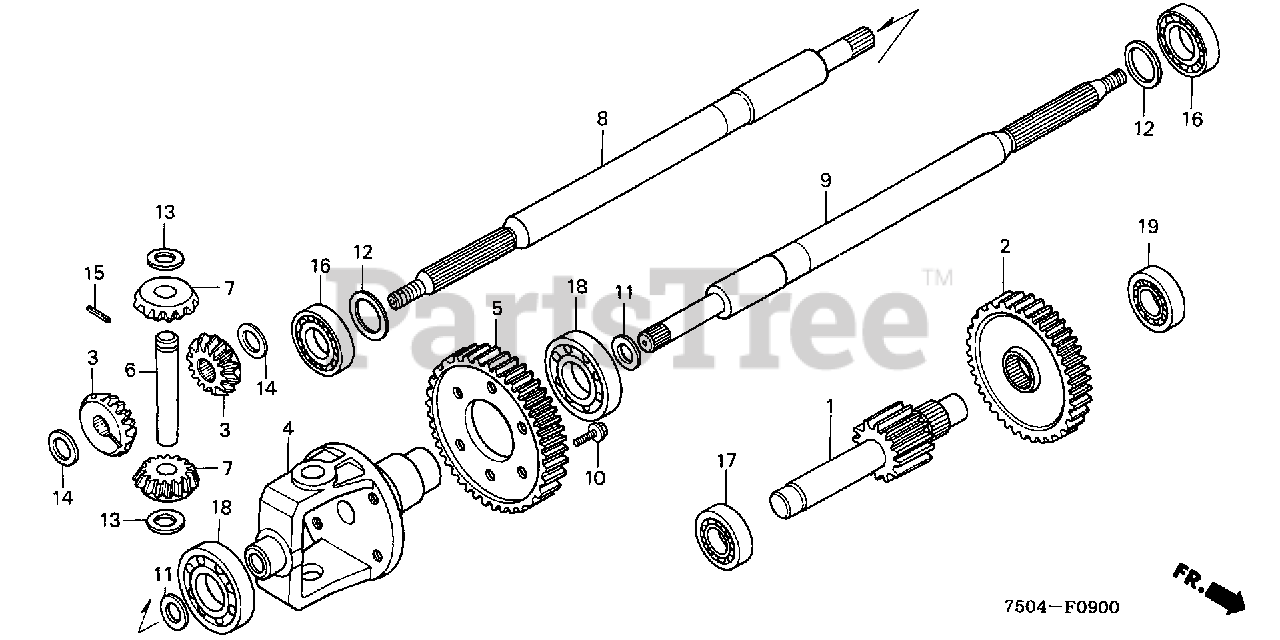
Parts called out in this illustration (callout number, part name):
1	COUNTERSHAFT
2	GEAR, COUNTERSHAFT DRIVEN (52T)
3	GEAR, DIFFERENTIAL (16T)
4	CASE, DIFFERENTIAL GEAR
5	GEAR, FINAL DRIVEN (49T)
6	SHAFT, DIFFERENTIAL PINION
7	PINION, DIFFERENTIAL (16T)
8	SHAFT, R. AXLE
9	SHAFT, L. AXLE
10	BOLT, SPECIAL (10X20)
11	WASHER, RR. AXLE
12	WASHER, SPECIAL
13	WASHER A, DIFFERENTIAL PINION
13	WASHER B, DIFFERENTIAL PINION
13	WASHER C, DIFFERENTIAL PINION
13	WASHER D, DIFFERENTIAL PINION
14	WASHER, DIFFERENTIAL GEAR
15	PIN, SPRING (4X32)
16	BEARING, RADIAL BALL (6205)
17	BEARING, RADIAL BALL (6203)
18	BEARING, RADIAL BALL (62/32)
19	BEARING, RADIAL BALL (6304)
